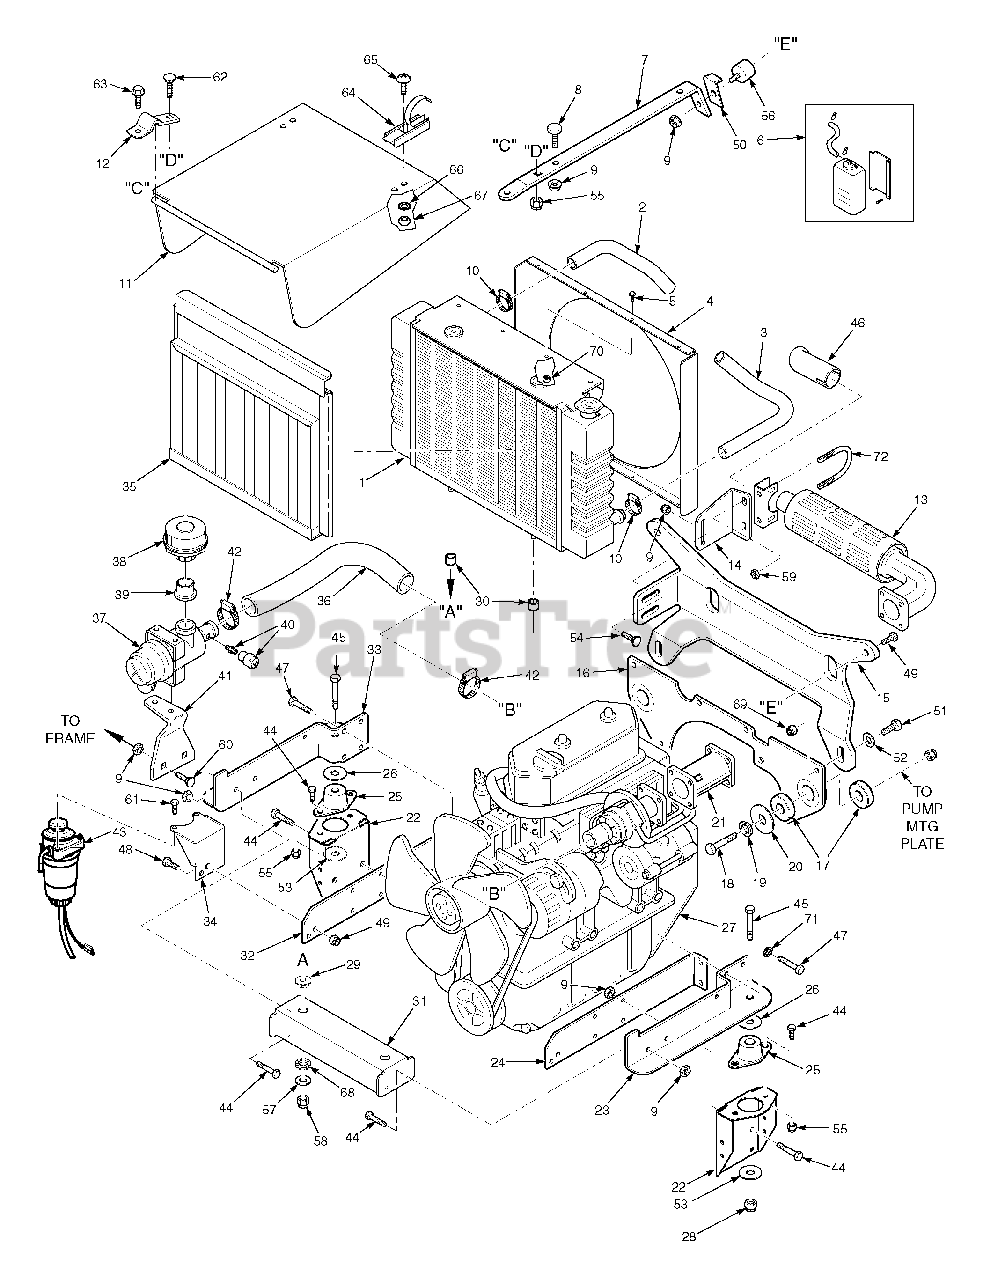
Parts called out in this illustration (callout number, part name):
1	Radiator
2	Hose, Upper Radiator
3	Hose, Lower Radiator
4	Shroud, Fan
5	Screw. #10-32 x 1/2"
6	Coolant Tank Assembly w/hose
7	Support Bracket, Hood
8	Bumper, Rubber
9	Nut, Serrated Flange 5/16-18
10	Clamp, 1-1/2" Dia.
11	Hood Weldment
12	Hinge, Hood
13	Muffler with Guard
14	Brace, Muffler Support
15	Mounting Bracket, Hood
16	Mounting Bracket Weldment, Rear Engine Mount
17	Engine ISO Mount, Rear
18	Bolt, Hex Head 1/2-13 x 3-1/2"
19	Lockwasher, 1/2" Spring
20	Flatwasher, 1/2-.531 x 2.0 x .25
21	Manifold Extension, Exhaust
22	Mounting Bracket, Engine
23	Mounting Bracket Weldment, Engine L.H.
24	Mounting Bracket, Engine L.H.
25	Engine ISO Mount, Front
26	Flatwasher, 1/2-.531 x 2.0 x .25
27	Engine, Briggs & Stratton 31hp Diesel (Spec. # )
28	Nut, Elastic Stop 1/2-13
29	Bushing, Radiator Isolator
30	Bushing, Radiator ISO Mount
31	Support Bracket, Radiator
32	Mounting Bracket, Engine R.H.
33	Mounting Bracket Weldment, Engine R.H.
34	Mounting Bracket, Water Seperator
35	Debris Screen
36	Hose, Air Intake
37	Air Cleaner Assembly w/mounting Band
38	Pre Cleaner, Engine Air
39	Adapter, Pre Cleaner
40	Indicator, Air Cleaner
41	Bracket, Air Cleaner
42	Clamp, Hose 2-1/2" Dia.
43	Fuel Filter, Water Seperator
44	Bolt, Hex Head 5/16-18 x 3/4"
45	Bolt, Hex Head 1/2-13 x 2-1/2"
46	Elbow, Exhaust
47	Bolt, Hex Head M8-1.25 x 3mm
48	Bolt, Hex Head 3/8-16 x 1-1/4"
49	Bolt, Hex Head 5/16-18 x 3/4"
50	Catch Bracket, Hood Latch
51	Bolt, Hex Head 3/8-16 x 1-1/4"
52	Flatwasher, 3/8-.391 x .938 x .105
53	Flatwasher, 1/2-.531 x 2.13 x .1345
54	Bolt, Carriage 5/16-18 x 1"
55	Nut, Elastic Stop 5/16-18
56	Rubber Isolator
57	Flatwasher, 7/16-.469 x 2.0 x .1345
58	Nut, Center Lock 7/16-14
59	Nut, Elastic Stop 5/16-18
60	Bolt, Carriage 5/16-18 x 3/4"
61	Bolt
62	Bolt, Carriage 5/16-18 x 1"
63	Bolt, Hex Head 5/16-18 x 3/4" Serr. Flange
64	Latch, Hood
65	Screw, #10-32 x .375
66	Lockwasher, #10 Spring
67	Nut, #10
68	Ring, Isolator
69	Nut, Elastic Stop 3/8-16
70	Nut, Elastic Stop #10-32
71	Lockwasher, 5/16 Spring
72	Muffler Clamp 1-1/2" Dia.
